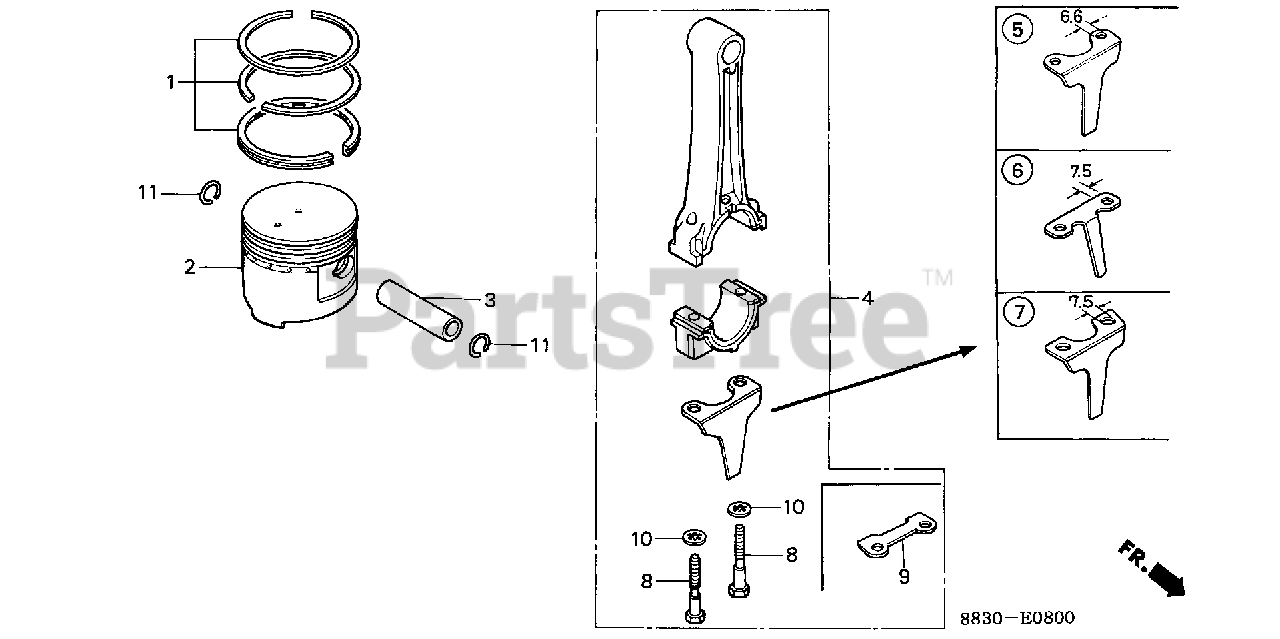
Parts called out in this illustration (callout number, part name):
1	RING SET, PISTON (STD) (NIPPON)
1	RING SET, PISTON (STD) (TEIKOKU)
1	RING SET, PISTON (0.25)
1	RING SET, PISTON (0.25) Use up to Engine SN 1477816.
1	RING SET, PISTON (0.50)
1	RING SET, PISTON (0.50) Use up to Engine SN 1152170.
1	RING SET, PISTON (0.75)
2	PISTON (STD)
2	PISTON (0.25)
2	PISTON (0.50)
2	PISTON (0.75)
3	PIN, PISTON
4	ROD ASSY., CONNECTING
5	DIPPER, CONNECTING ROD
5	DIPPER, CONNECTING ROD (NOT AVAILABLE)
6	DIPPER, CONNECTING ROD
7	DIPPER, CONNECTING ROD (NOT AVAILABLE)
8	BOLT, CONNECTING ROD (6MM)
8	BOLT, CONNECTING ROD (6MM) (NOT AVAILABLE)
8	BOLT, CONNECTING ROD (7MM)
9	WASHER B, CONNECTING ROD
10	WASHER, LOCK (6MM) (N/A: SEE ASSEMBLY)
10	WASHER, LOCK (7MM)
11	CLIP, PISTON PIN (15MM)
